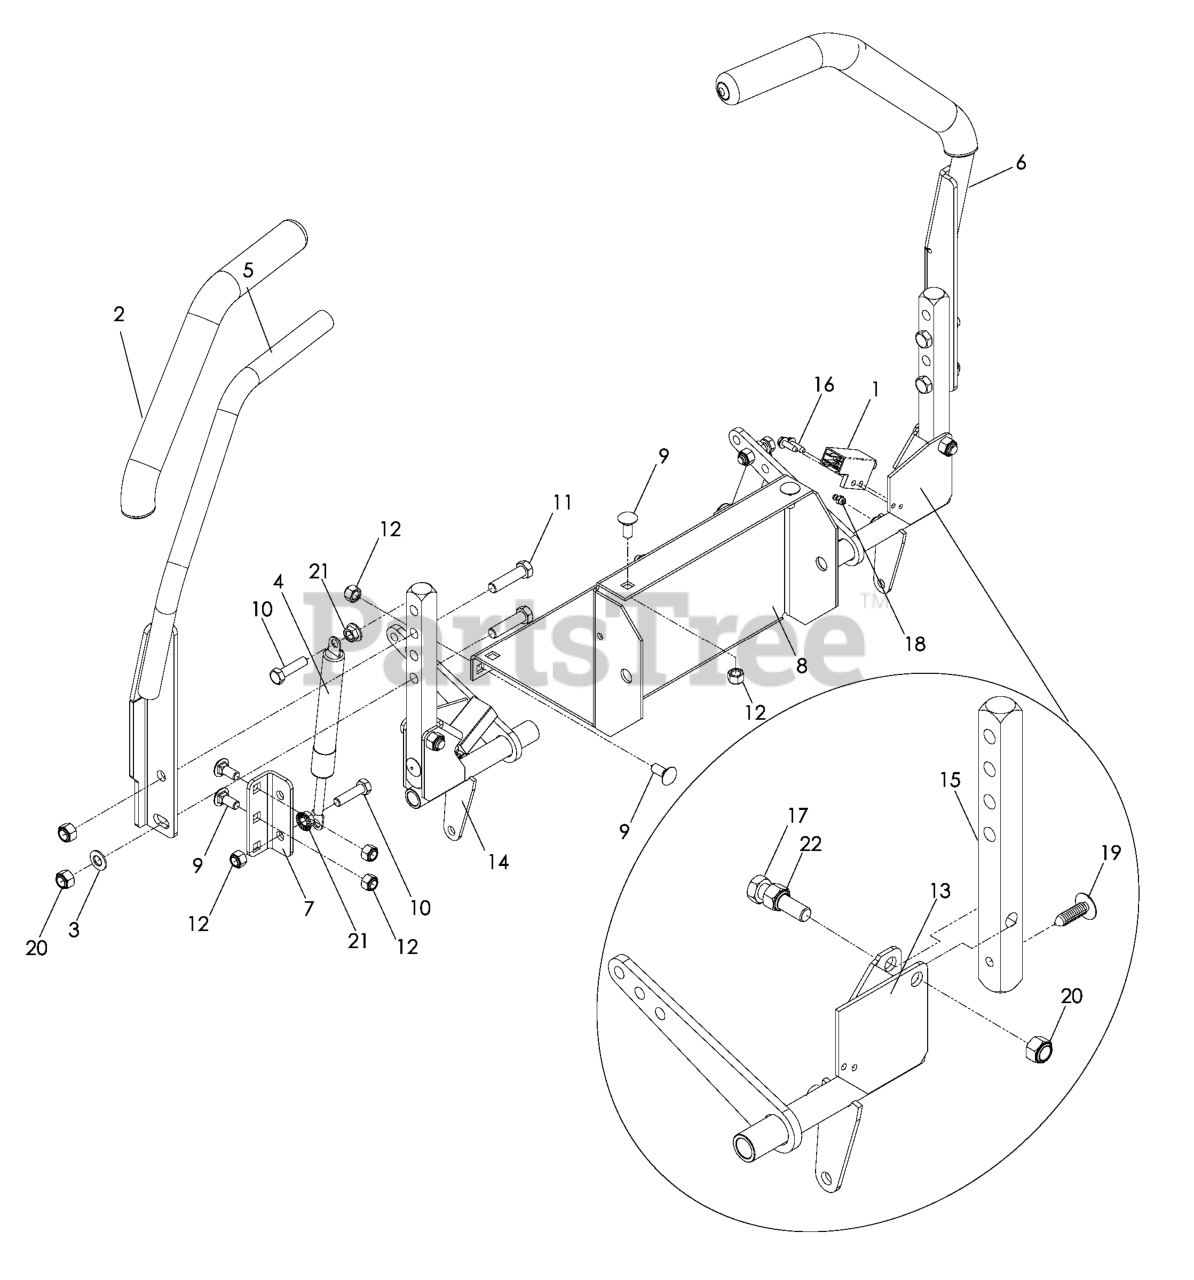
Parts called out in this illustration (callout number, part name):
1	SWITCH, INTERLOCK
3	WASHER, 3/8 DISC SPRING SPEC
5	RT DRIVE LEVER WLDMT
6	LT DRIVE LEVER WLDMT
7	DAMPENER BRACKET
8	BATTERY TRAY
9	BOLT 5/16C X 3/4" CARRIAGE
10	HCS 5/16C X 1 1/4
11	HCS 3/8C X 1 1/2
12	NUT 5/16 NYLOC
13	CONTROL WELDMENT, LEFT
14	CONTROL WELDMENT, RIGHT
15	CONTROL ARM
16	SCREW #10 X 1/2 SELF TAPPING
17	HCS 3/8-16 X 2-1/2 TPBLT
18	ZERK
19	RIVET, NYLON PUSH-IN
20	NUT 3/8-16 NYLOC
21	NUT 5/16C WHIZ
22	NUT 3/8C CENTERBLOCK
